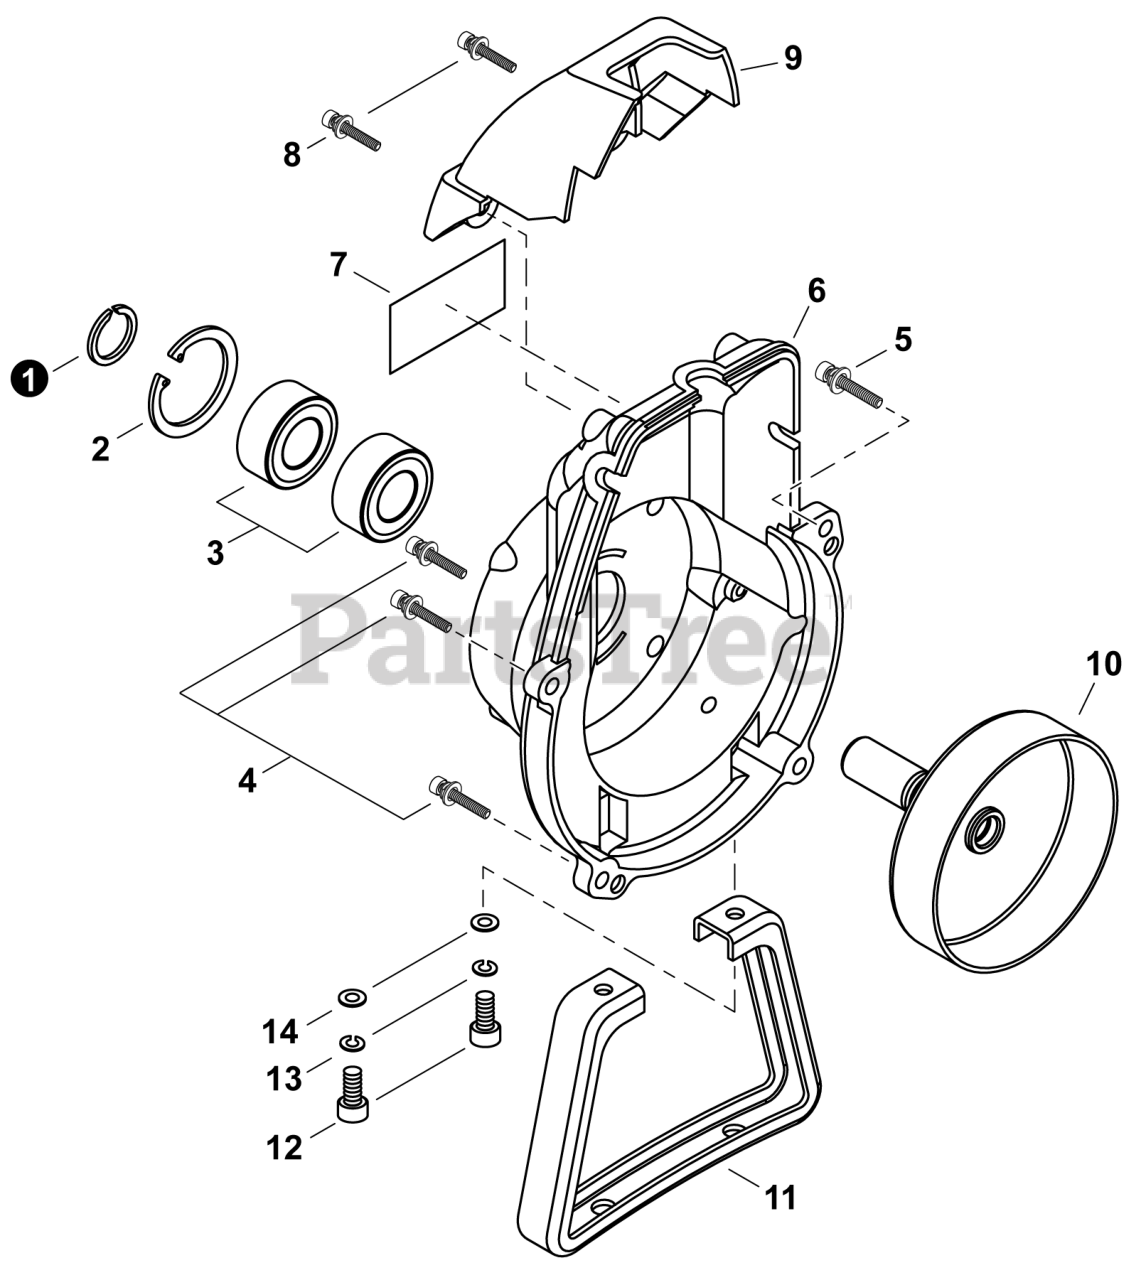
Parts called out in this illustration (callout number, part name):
1	RING, SNAP
2	RING, SNAP 32
3	BEARING, BALL 6002 DDU
4	BOLT 5x20
5	BOLT M5x30
6	COVER, FAN
7	LABEL - MODEL B452
8	BOLT M4x16
9	GUARD, TOP
10	DRUM, CLUTCH
13	WASHER, SPRING 5
14	WASHER 5.5x12x0.8
